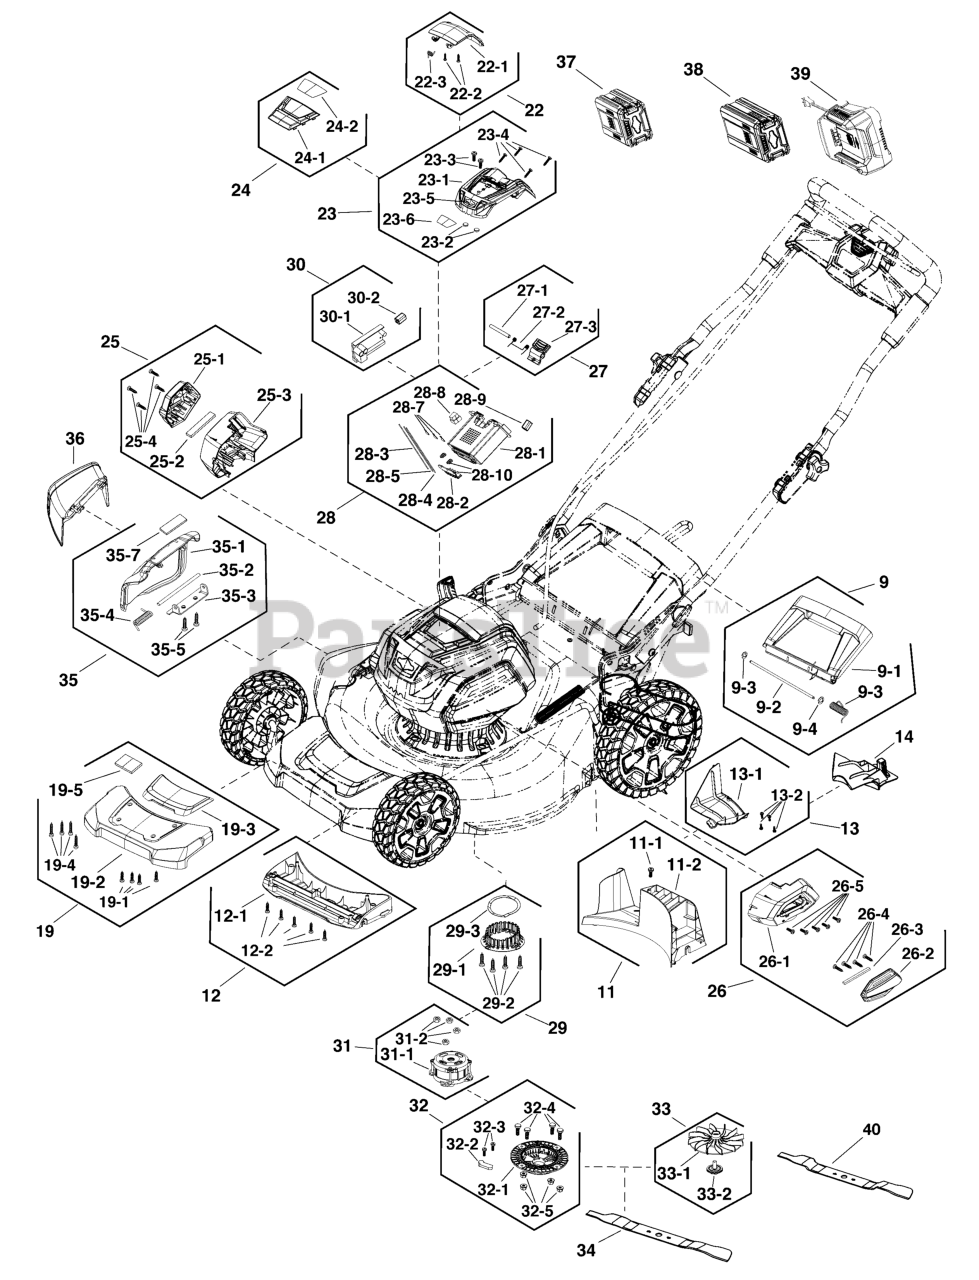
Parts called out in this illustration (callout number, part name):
9	KIT, REAR COVER ASSEMBLY
9-1	COVER, Rear
9-2	PIN
9-3	SPRING
9-4	WASHER, Split
11	KIT, REAR BAFFLE
11-1	REAR BAFFLE
12	KIT, Front Bulkhead
12-1	BAFFLE, Front
13	KIT, Transition
13-1	CASING
14	KIT, Mulching Plug
19	KIT, Front Panel
19-2	BUMPER
19-3	COVER, Bumper
19-5	DECAL
22	KIT, Battery Cover
22-1	COVER, Battery
22-3	SPRING
23	KIT, Top Cover
23-1	COVER, Top
23-2	MAGNET
23-5	B&S LOGO
23-6	BATTERY LABEL
24	KIT, Cover
24-1	TOP COVER
24-2	SHROUD
25	KIT, RIGHT COVER
25-1	COVER, Right
25-2	COVER, Right
25-3	SCREEN, Dust
26	KIT, Left Cover
26-1	COVER, Left
26-2	HOUSING, Left
26-3	SCREEN, Dust
27	KIT, RELEASE BUTTON
27-1	PIN
27-2	SPRING
27-3	BUTTON
28	KIT, Battery Compartment
28-1	HOUSING, Battery
28-2	TERMINAL
28-3	WIRE, Red
28-4	WIRE, Yellow
28-5	WIRE, Black
28-7	CONNECTOR
28-9	CONTACT
28-10	SPRING
29	KIT, BASE
29-1	BASE
29-3	SEAL
30	KIT, PCB
30-1	PCB
30-2	MAGNET
31	KIT, Motor
31-1	MOTOR
31-2	NUT
32	KIT, MOTOR BASE
32-1	MOTOR BASE
32-2	DISC, Tension
32-4	BOLT
32-5	NUT
33	KIT, Fan
33-1	FAN
33-2	KIT, Bolt
34	KIT, Blade
35	KIT, SIDE DISCHARGE COVER
35-1	SIDE DISCHARGE COVER
35-2	PIN
35-3	BRACKET
35-4	SPRING, Torsion
35-5	BOLT
35-7	LABEL
36	KIT, Discharge Chute
37	* BATTERY, 2.0, 82V EU/AU
38	* BATTERY, 4.0, 82V EU/AU
39	* CHARGER, Battery, EU
40	BLADE, Mulching, 19"
